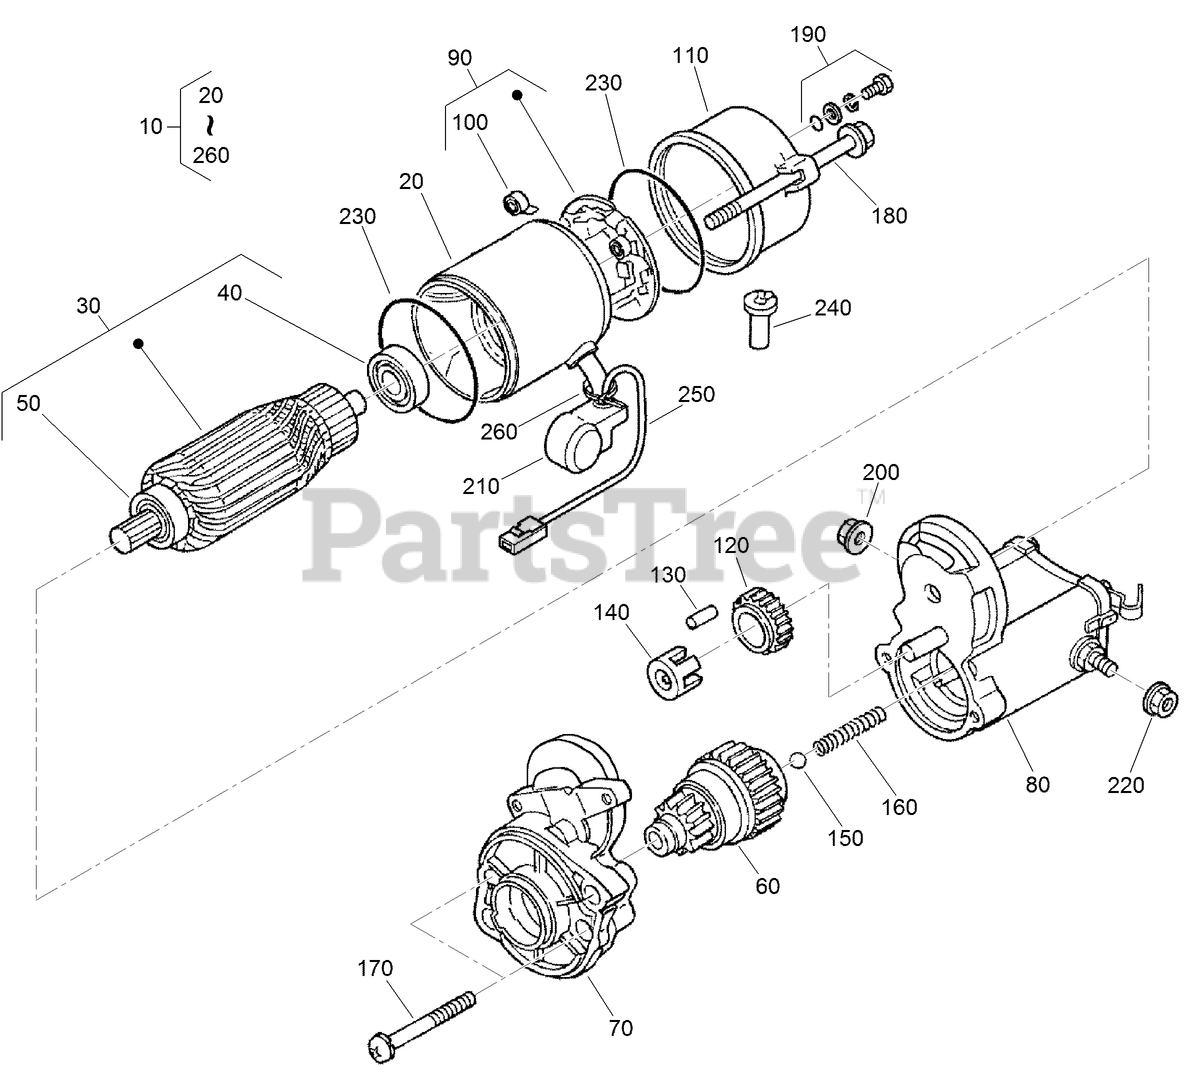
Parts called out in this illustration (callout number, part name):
10	STARTER
30	ARMATURE
40	BEARING
50	BEARING
60	CLUTCH ASM
70	HOUSING ASM
80	MAGNETIC SWITCH ASM
90	HOLDER-BRUSH
100	SPRING-BRUSH
110	FRAME END ASM
130	ROLLER
140	RETAINER
160	SPRING
180	BOLT-THROUGH
190	BOLT ASM
200	NUT-HEX
210	COVER
220	NUT-HEX
230	O-RING
240	PIPE-DRAIN
250	CORD-SOLENOID, STOP
260	BAND-COVER
